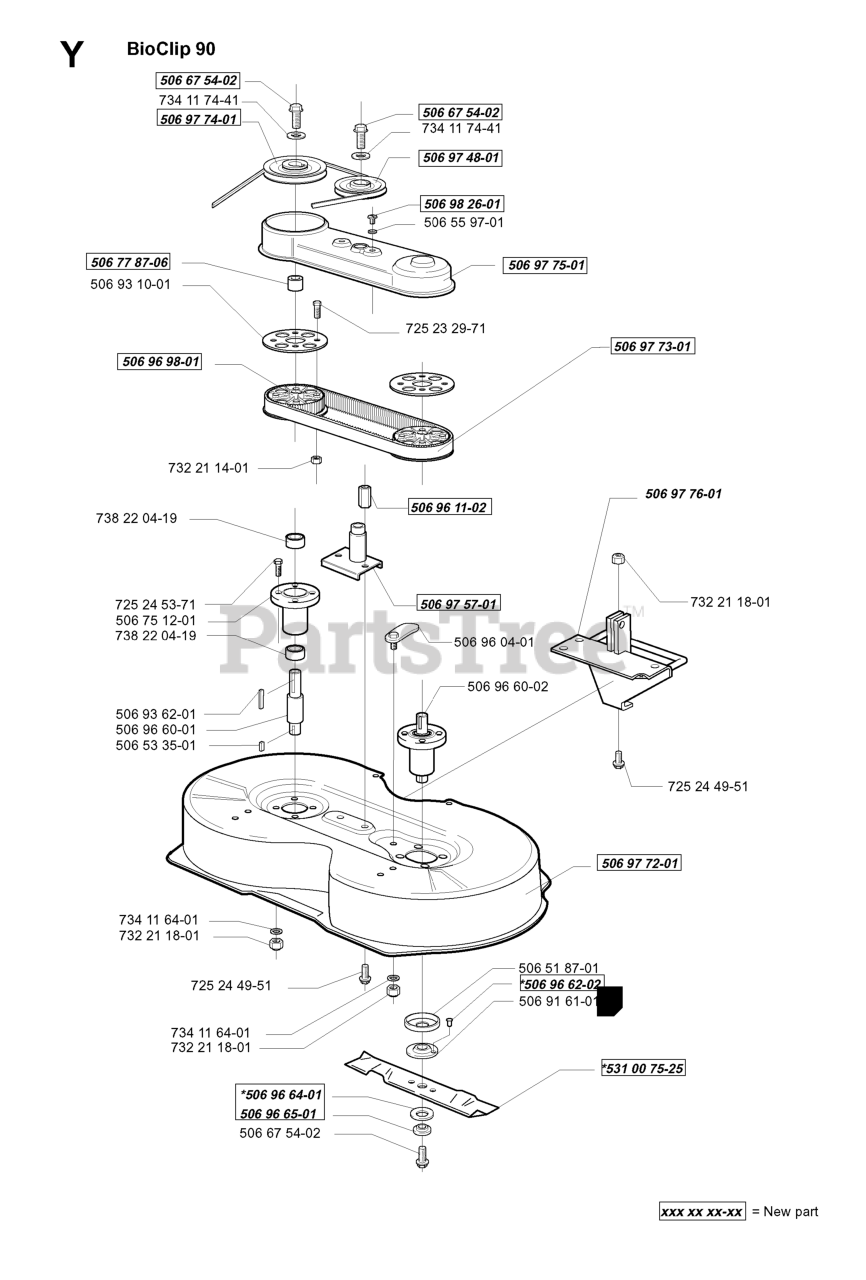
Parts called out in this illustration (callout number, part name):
2	KEY 1/4 X 2.5
6	COTTER PIN
7	HUB ASMBLY
15	WASHER
17	SPRING.ROD.BRAKE
20	NUT.HEX.1/2-20
22	SHAFT ARM ASMBLY
23	KNOB.DELUXE.(PISTOL.GRIP).BLAC
28	NUT
30	WASHER
33	E RING HYT
34	PLUNGER CAP
35	PARKING BRAKE ROD
36	SPRING DRIVE GROUND
39	Screw, Fin. #10-24 x 1
40	ACT-SWITCH T
41	LOCKNUT
42	COVER, PEDAL (1 2)
43	BOLT.HEX.1/4.X.3/4.DICHROMATE
44	BRKT SWITCH GT
45	LOCKNUT.NYLOC.1/4-20
46	RETAINER SPRING
47	CLUTCH ROD
49	Washer 13/32 x 7/8 x 13 Gauge
50	FLAT IDLER PULLEY
51	NUT
52	PULLEY.IDLER.V.
54	CLUTCH ARM ASSY
55	BEARING LT (2 2)
58	BOLT.HEX.7/16-14.FINISHED
64	SHAFT CLUTCH/BRAKE PEDAL
66	WASHER.BLADE
67	WASHER
68	ROLL PIN STD
70	CONSOLE, SHIFT HYD
71	PLATE CONSOLE SHIFT
72	NUT.71038.31-18.HEX.NYLOCK
73	Bolt Fin Hex 5/16-18 x 3
74	SCREW.HI-LO.CONSOLE
75	Nut, Lock Hex 7/16 Unc
76	BRACKET TRANSAXLE
77	BOLT
79	BOLT.CARR.5/16-18X5/8.SHORT
80	TORQUE BRACKET RH
81	SCREW
82	BRACKET MOUNT TORQUE/FAN
83	STRAP TORQUE MID
85	Screw #10-24 x 1-1/4
86	FAN 7" HYDRO
87	ADAPTOR.FAN.TRANSAXLE.VGTH
88	IDLER PULLEY
89	Nut, Crownlock Hex 7/16-14 unc
90	KEEPER.BELT
91	SCREW.HXWSH.3/8
92	BOLT
93	LINK ASM SHIFT
94	FASTENER.XMAS.TREE
95	Screw Set 5/16-18 x 1.75
98	SHIFT BRACKET
99	SCREW LT
102	NUT
103	JAM NUT TI
104	BRACKET IDLER
105	SCREW CRT
106	O-RING KIT 70110
107	LINE.VENT.HYDRO-GEAR
108	CAP, VENT ASSY
109	RETURN SPRING
110	HINGE SCREW
